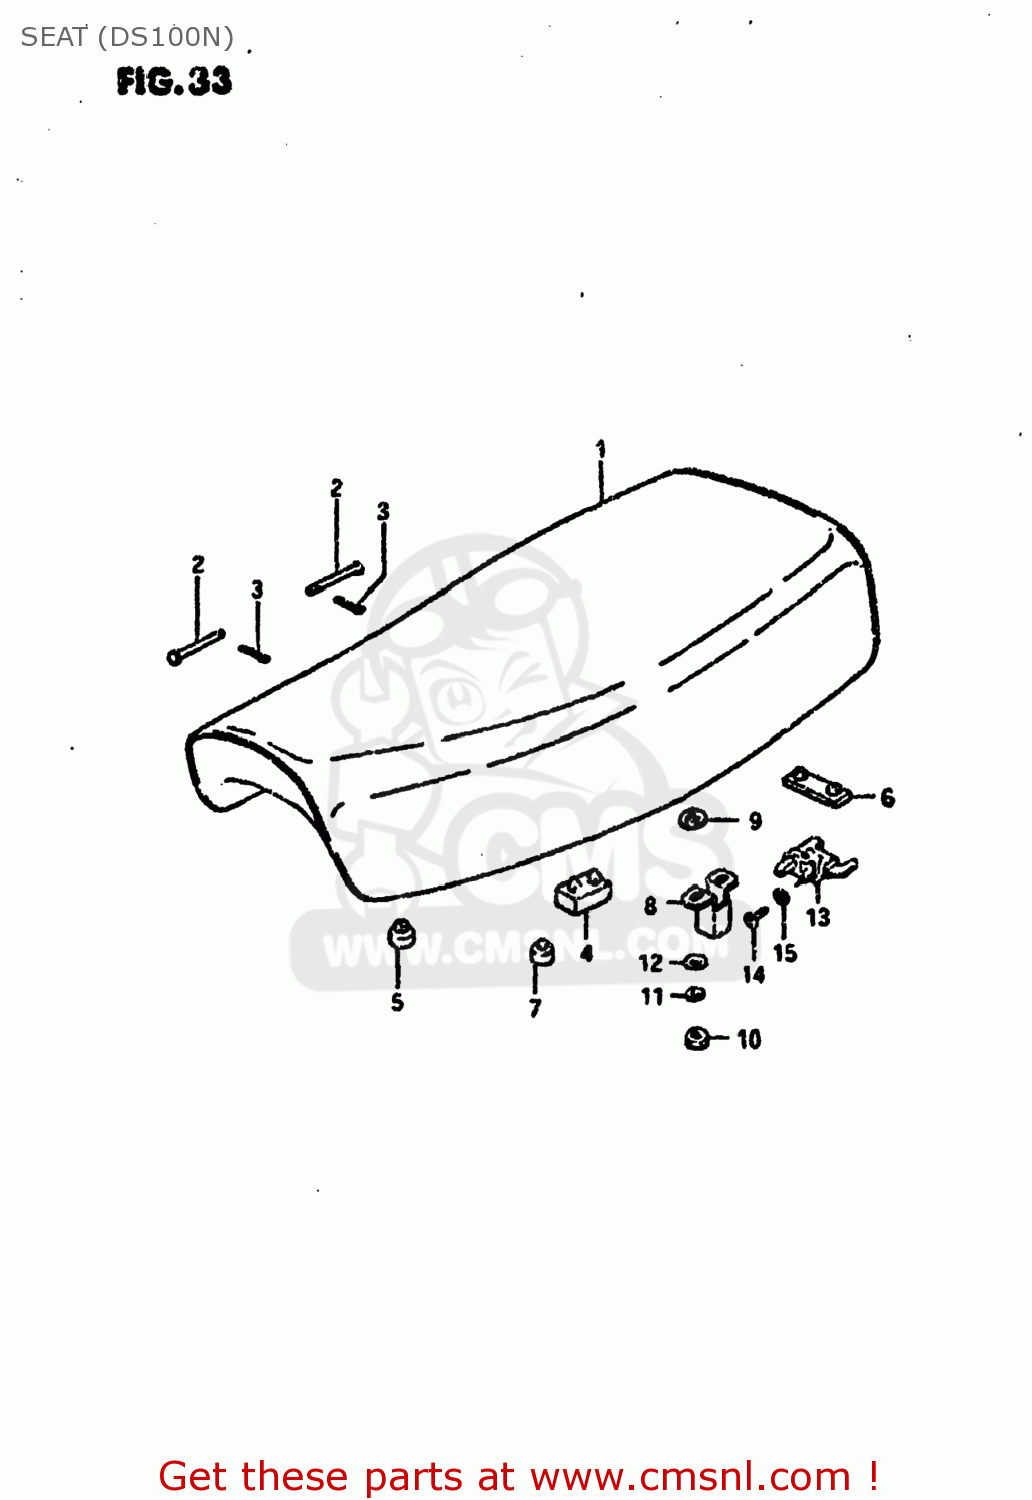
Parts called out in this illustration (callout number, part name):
1	SEAT ASSEMBLY
2	PIN
3	PIN
4	CUSHION
5	CUSHION(11.5X22X20)
6	CUSHION
7	CUSHION
8	PLATE,CLAMP GUIDE
9	WASHER(8.5X18X1)
10	NUT
11	LOCK WASHER
12	WASHER
13	LOCK ASSEMBLY,SEAT
14	SCREW
15	LOCK WASHER
